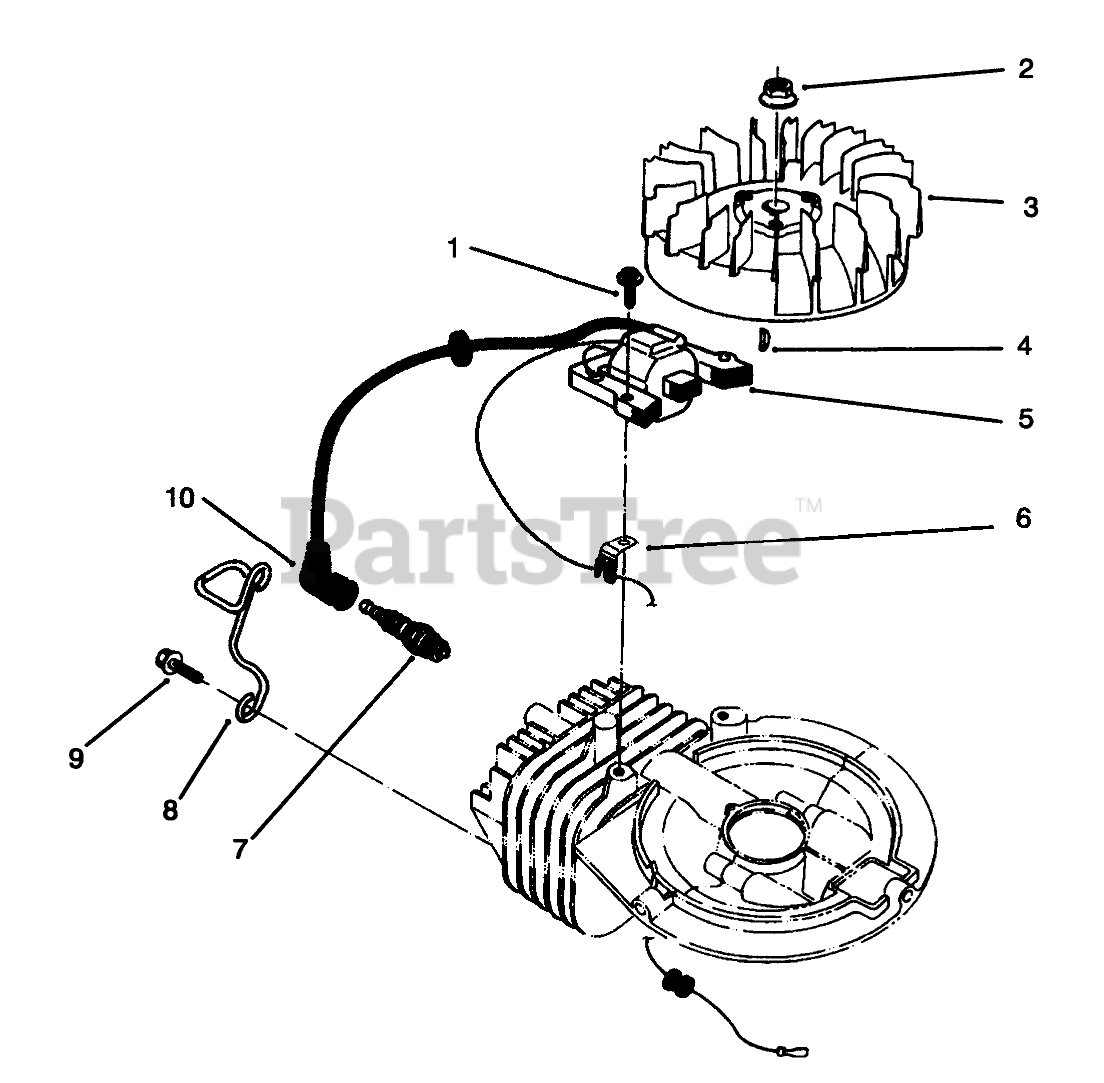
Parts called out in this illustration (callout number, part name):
1	SCREW
3	FLYWHEEL
5	COIL-MAGNETO
6	CLAMP
7	Sparkplug
8	PROTECTOR-PLUG
9	SCREW
10	CAP-SPARKPLUG
